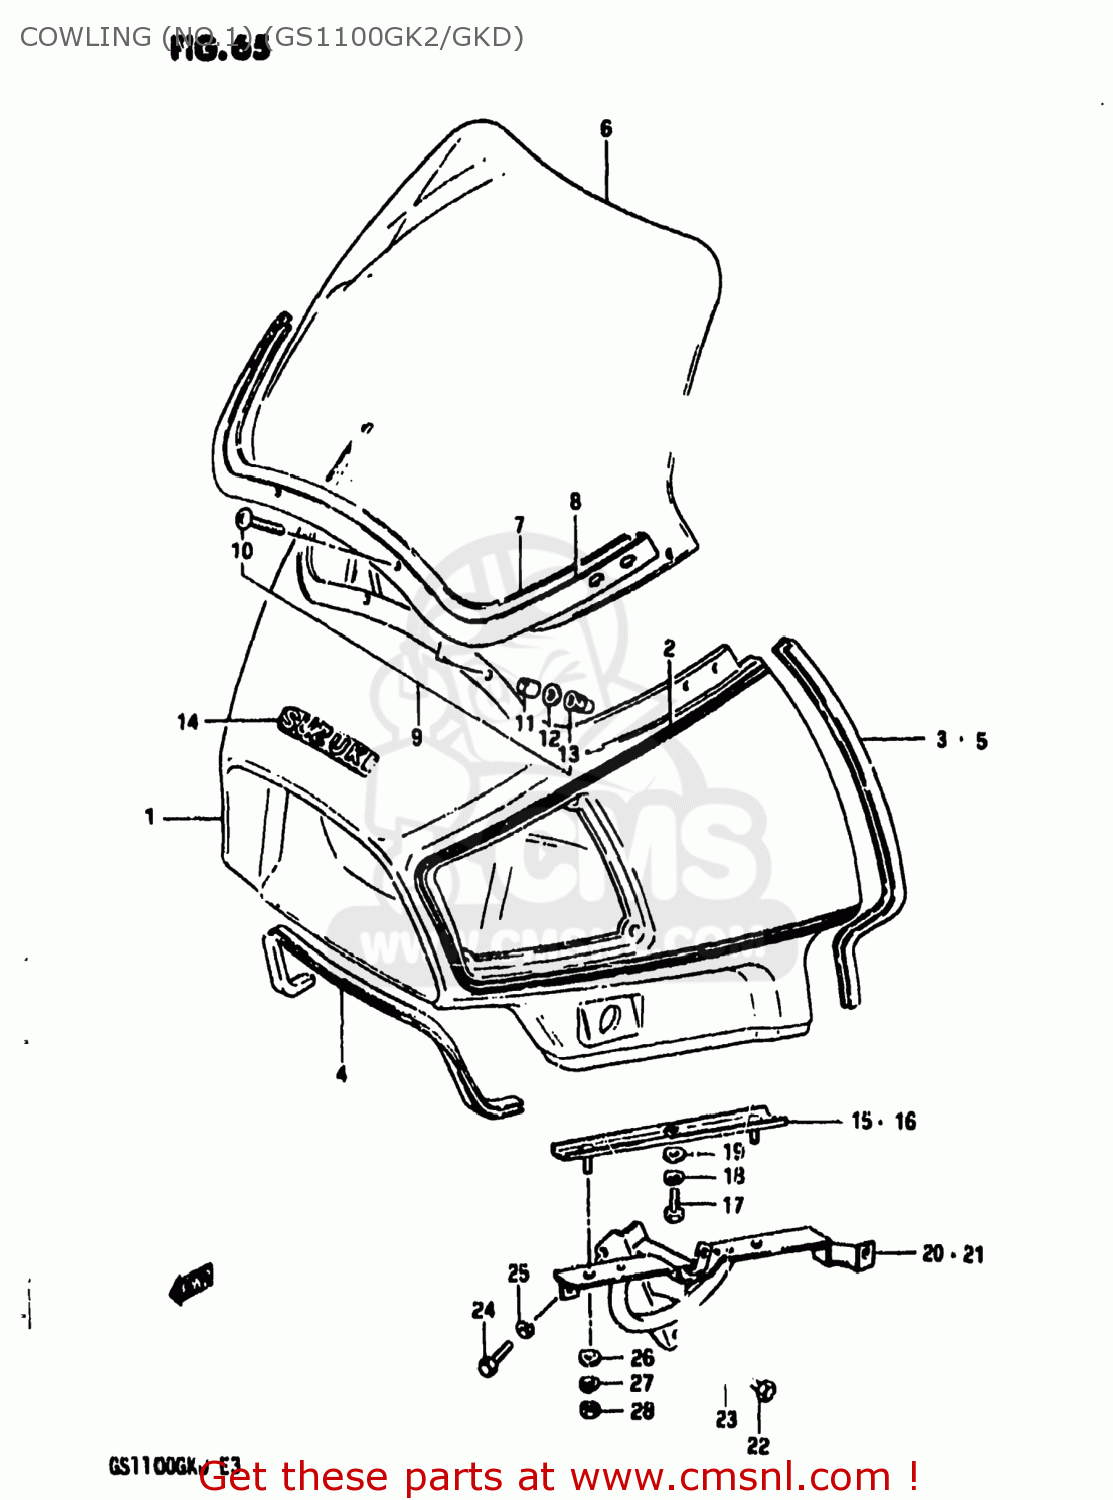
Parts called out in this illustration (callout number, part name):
1	BODY ASSEMBLY,COWLING
2	TAPE SET,COWLING
3	MOLDING,COWLING,RIGHT
4	MOLDING,LOWER
5	MOLDING,COWLING,LEFT
6	WINDSHEILD,COWLING
7	CUSHION,WINDSHEILD
8	PLATE,WINDSHEILD
9	BODY ASSEMBLY,COWLING
10	SCREW
11	SPACER(6.3X9.3X16.5)
12	WASHER (6.5X20X1.2)
13	NUT
14	EMBLEM,COWLING
15	PLATE,COWLING FITTING
16	PLATE,COWLING FITTING
17	BOLT
18	LOCK WASHER
19	WASHER
20	BRACE,COWLING
21	BRACKET,COWLING,LEFT
22	BOLT
23	LOCK WASHER
24	BOLT
25	LOCK WASHER
26	WASHER
27	LOCK WASHER
28	NUT
